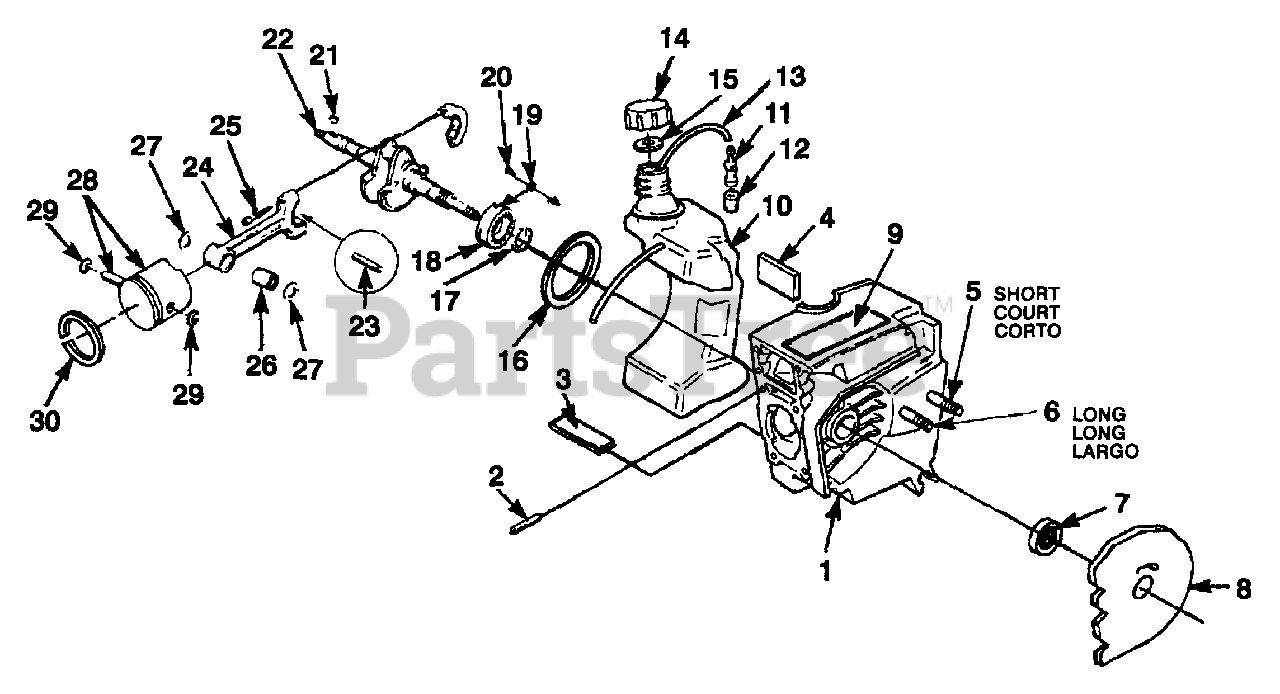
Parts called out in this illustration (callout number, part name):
1	CRANKCASE
2	STUD - Cylinder
3	SPACER - Fuel Tank
4	SPACER - Fuel Tank
5	BOLT - (5/16-18 X 2 1/4")
6	BOLT - (5/16-18 X 2 1/2")
8	SAW DUST SHIELD
9	DECAL - Instruction/Warning
10	FUEL TANK
11	FILTER - Fuel
12	ELEMENT - Filter
13	TUBING - Rubber (13")
14	CAP - Fuel
15	GASKET - Fuel
16	"O" RING
17	RING - Retaining
18	BEARING - Ball
19	WASHER - Lock
20	SCREW - Torx
21	KEY - Woodruff
22	CRANKSHAFT
23	BEARING - Needle
24	ROD - Connecting
25	SCREW - Hex Hd. (8/32 X 1/2")
26	BEARING
28	PISTON & PIN ASSY.
29	RING - Retaining
30	PISTON RING
